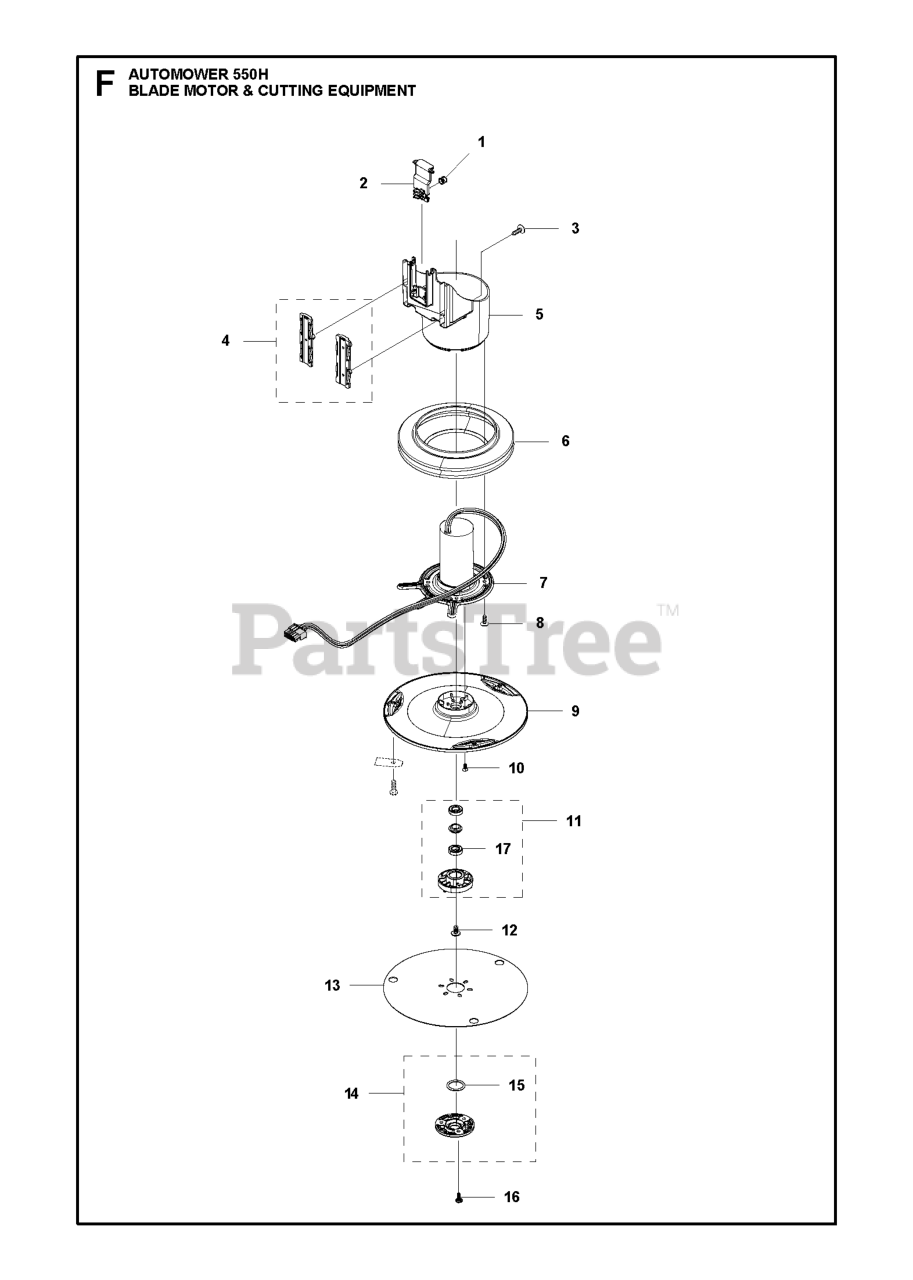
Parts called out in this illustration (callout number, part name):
1	SPRING LINK
2	LINK MOTOR HOUSING
3	SCREW 14MM
4	BEARING KIT
5	HOUSING CUTTING MOTOR
6	BELLOWS CUTTING SYSTEM
7	MOTOR ASSY JE
8	SCREW 14MM
9	CUTTING DISC
10	SCREW TORX M4X8 8.8 NYLON PATC
11	BEARING HOUSING ASSY
13	SKID PLATE
14	COVER KIT BEARING
15	O-RING 20X2,5 MM
16	SCREW 14MM
17	BALL BEARING 2 RS,TIGHT CLEAR
17	BALL BEARING BALL BEARING 535
